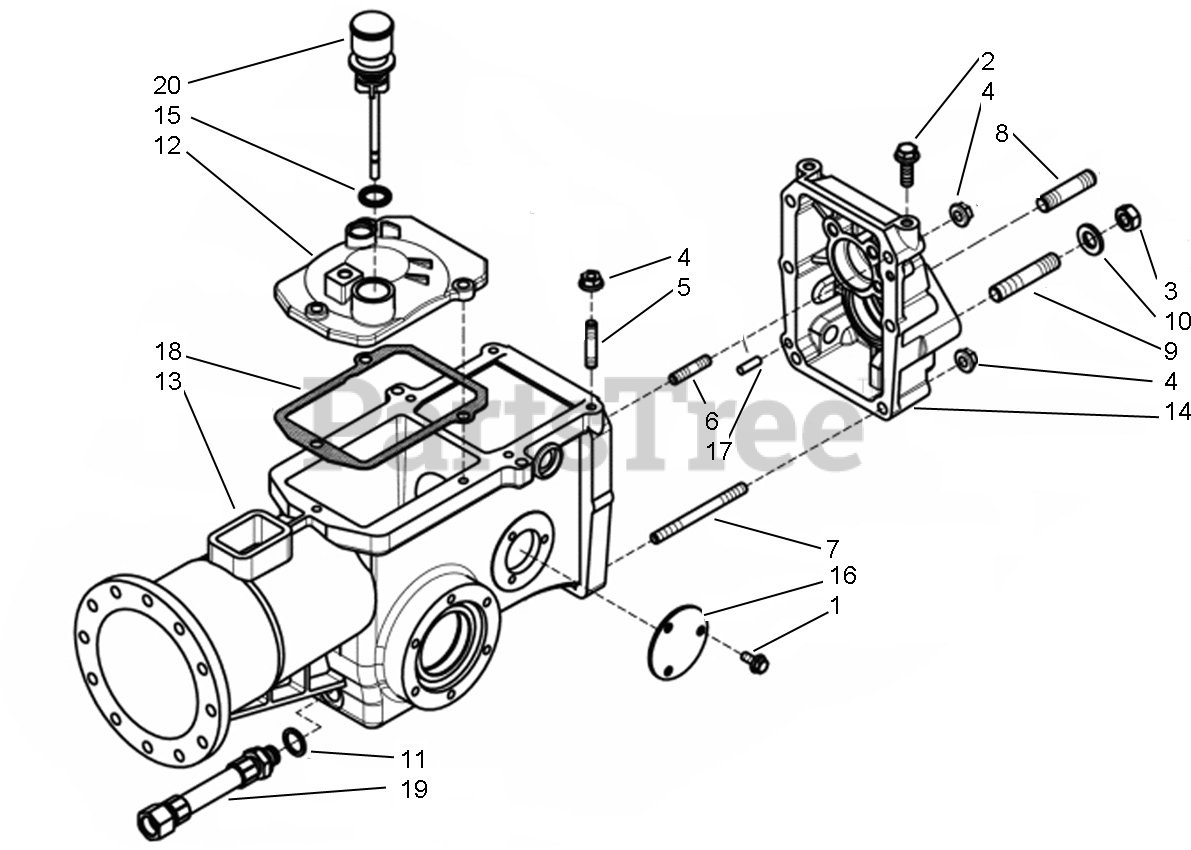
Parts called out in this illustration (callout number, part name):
1	SCREW
2	SCREW TE C/F M8X20
3	NUT M12X1,25
4	SELF LOCK NUT M8 7
5	STUD BOLT M8X38X14X20
6	STUD BOLT M8X58X16X16
7	STUD BOLT M8X68X14X36
8	PTO STUD
9	PTO STUD
10	WASHER 13X24X2,8
11	COPPER WASHER 16,7X22/1,5
12	GEARBOX HOUSING COVER
13	BOX CASING
14	REAR COVER
15	RUBBER RING
16	COVER
17	CYLINDRICAL PLUG
18	COVER GASKET
20	DIP STICK
